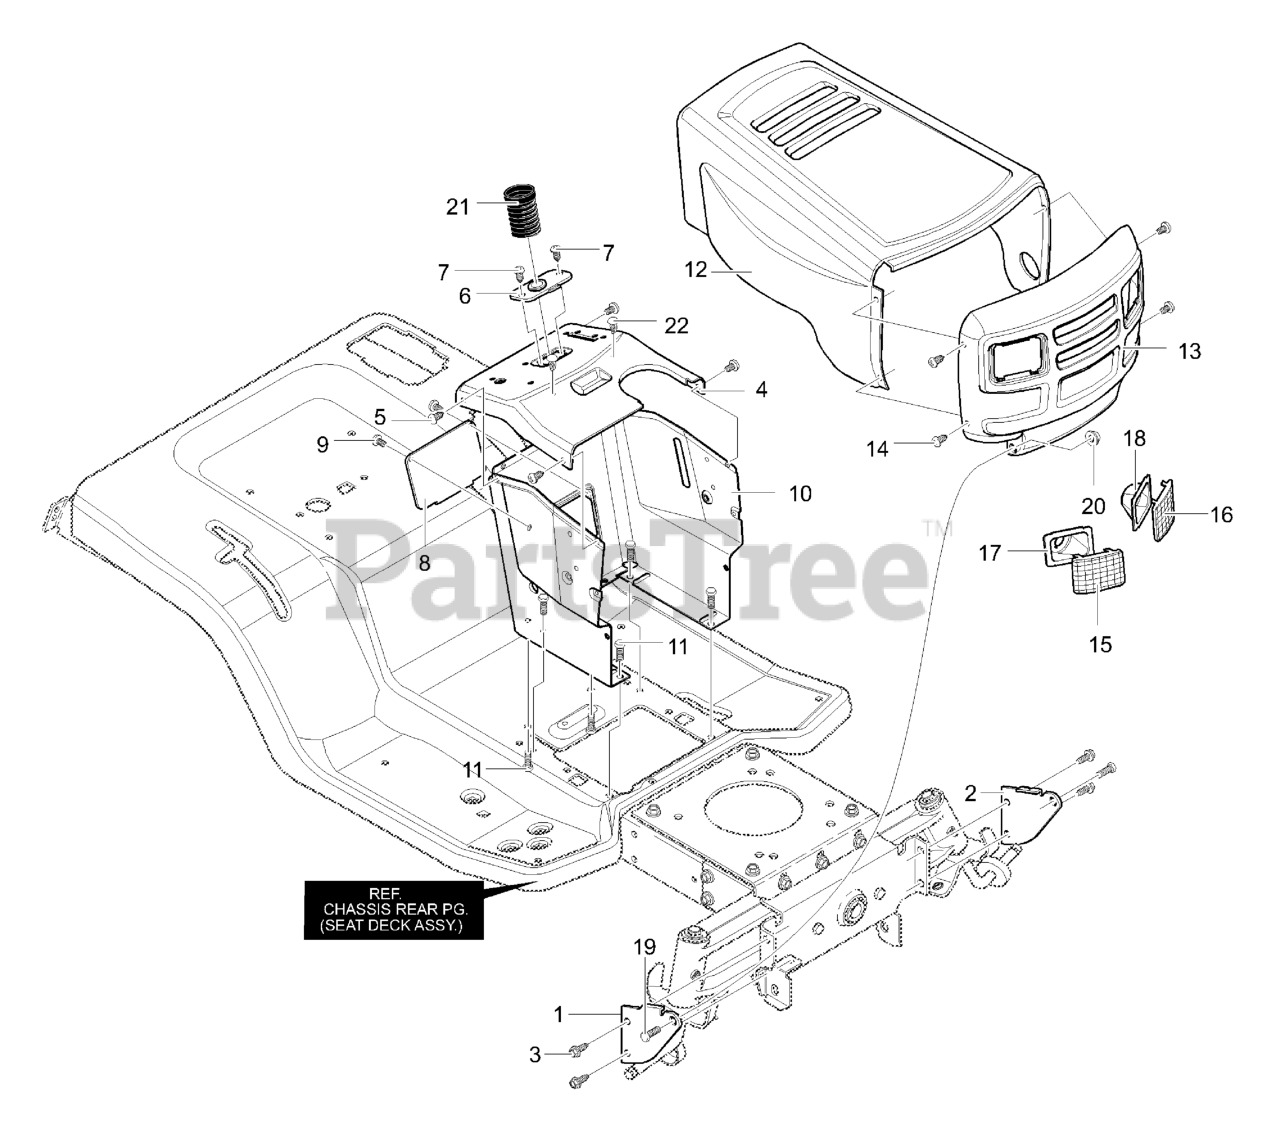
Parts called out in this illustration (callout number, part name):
1	Support, Grille RH
2	Support, Grille LH
3	Screw, 5/16-18 x 0.75
5	Screw, 10-24x.500
6	Steering Bracket
7	Screw, 1/4-14x.50
8	Accesss Panel
9	Screw, 10-24x.500
10	Dash Support
11	Screw, 5/16-18 x 0.75
14	Screw, 10-24x.500
15	Lens, RH
16	Lens, LH
17	Reflector, Headlight
18	Reflector, Headlight
19	Bolt, Shoulder
20	Nut, 3/8-16 Hwdfllk Whiz
21	Bellows, Steering Post
22	Bumper
